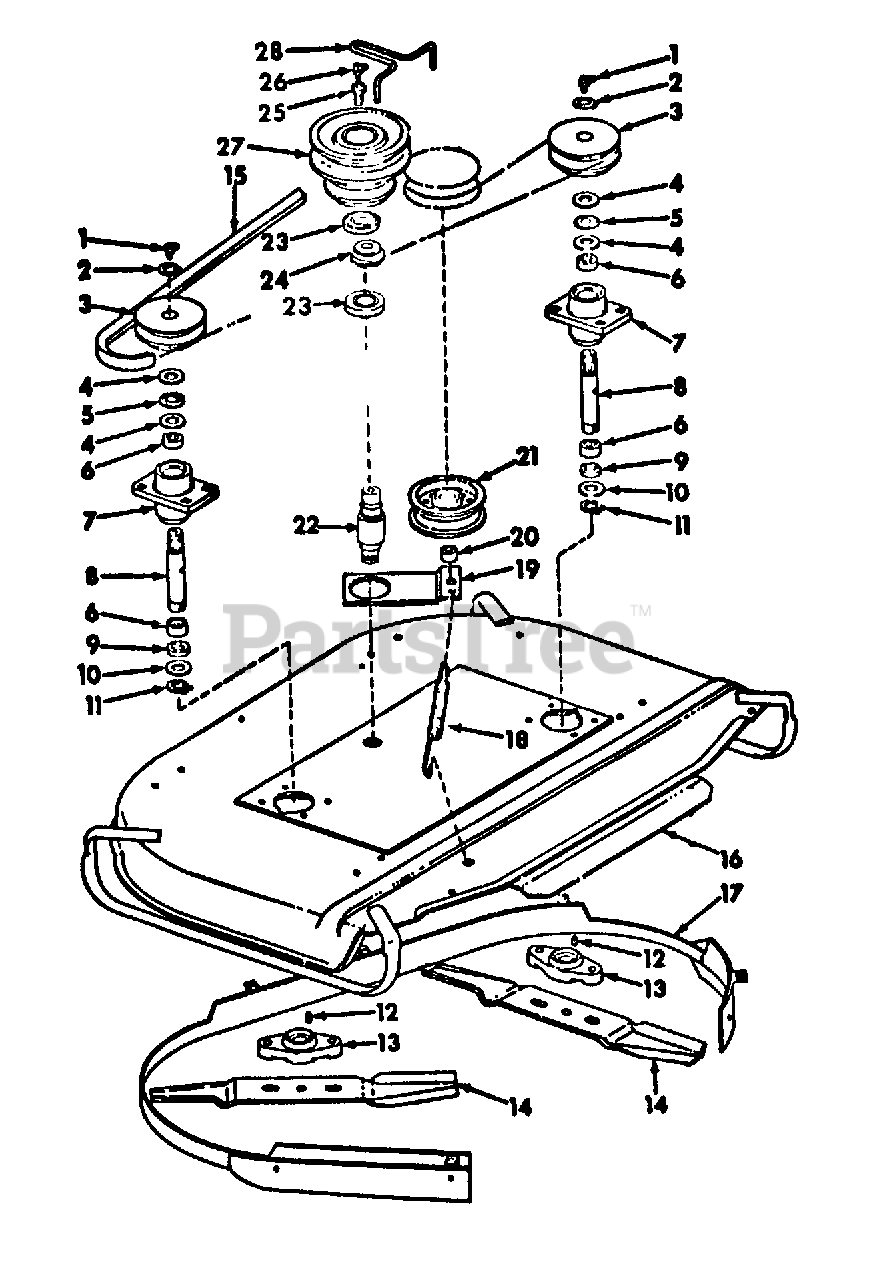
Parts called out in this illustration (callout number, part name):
1	FITTING, 3/16 ANGLE DRIVE LUB
2	RING, RETAINING
3	PULLEY, BLADE
4	WASHER, THRUST
5	BEARING, NEEDLE
6	BEARING, NEEDLE
7	HOUSING, BLADE SHAFT
8	SHAFT, NEEDLE
9	SEAL, GREASE
10	WASHER, THRUST
11	RING, RETAINING
12	KEY, 3/16 X 1/2 SQ PARALLEL
13	ADAPTER, BLADE
14	BLADE, 32 IN. MOWER -HARD SURFACED-
15	BELT, BLADE DRIVE
16	HOUSING ASSY, MOWER
17	SHROUD ASSY, MOWER
18	SPRING, IDLER
20	SPACER, IDLER PULLEY
21	IDLER, BALL BRG
22	BEARING, FAN & WATER PUMP TYPE
23	RING, 2.072 INT RET
24	SPACER, PULLEY
25	BOLT, END
26	FITTING, 3/8 45 DEG DRIVE TYPE LUB
27	PULLEY, CENTER SPINDLE
28	GUIDE, PTO BELT
